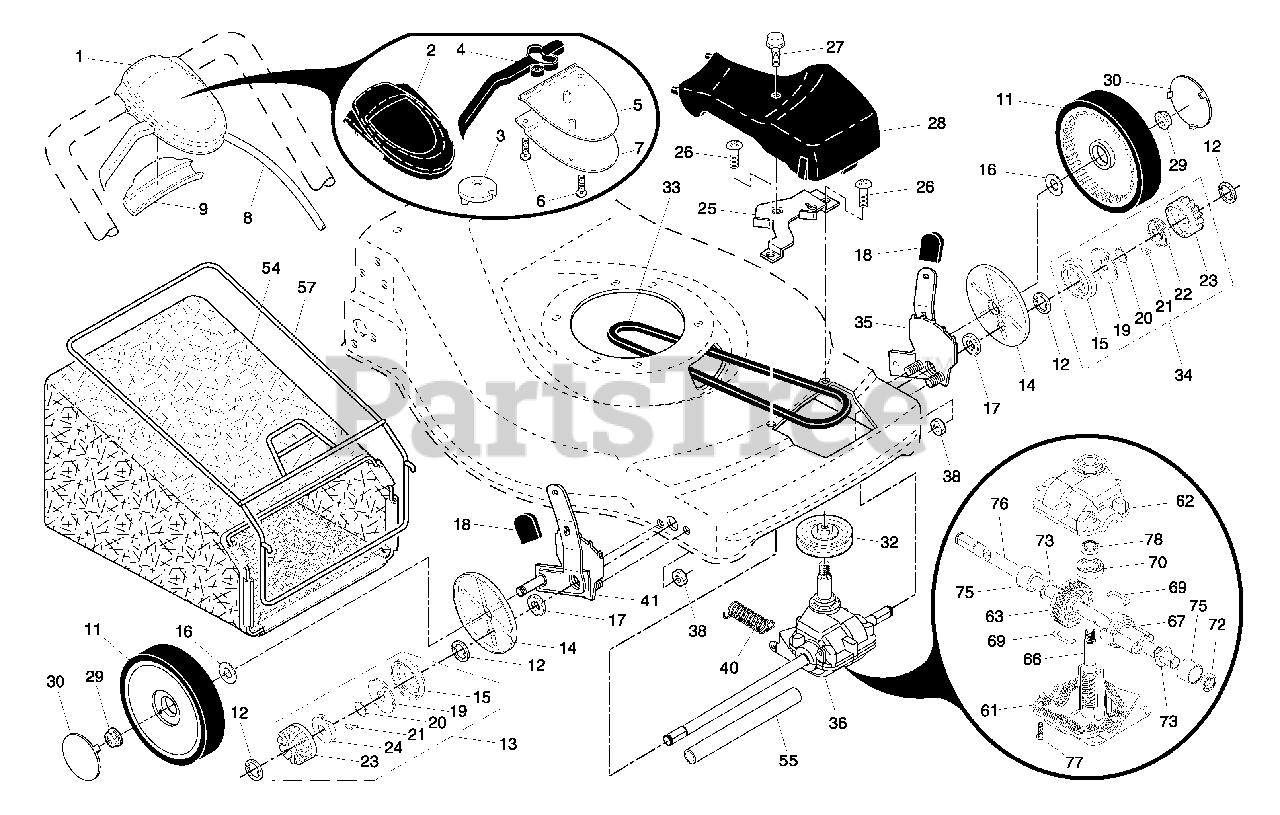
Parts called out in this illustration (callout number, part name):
1	Drive Control Assembly
2	Cover, Drive Control, Top
4	Lever, Drive Control
5	Cover, Drive Control, Bottom
6	Screw, Torx Head #8 x 5/8
7	Mounting Bracket, Drive Control
8	Cable, Drive Control
9	Cap, Drive Control, Bottom
11	Wheel & Tire Assembly
13	Pinion Assembly, RH
14	Dust Cover
15	Seal, Friction
16	Washer, Flat 3/8
17	Bearing, Wheel Adjuster
18	Selector Knob
19	Disc, Drive
20	Spring, Torsion
22	Retainer, Drive, LH
23	Gear, Pinion
24	Retainer, Drive, RH
25	Belt Guide Bracket
26	Screw
27	Pan Head Tapping Screw #10-24 x 2-3/4
28	Drive Cover
29	Locknut, Hex
30	Hubcap
31	Nut, Hex, Flanged
32	Drive Pulley
34	Pinion Assembly, LH
35	Kit, Wheel Adjuster, LH
36	Gear Case Assembly, Complete
38	Locknut, Hex 1/4-20
40	Spring
41	Kit, Wheel Adjuster, RH
54	Grassbag Assembly
55	Driveshaft Cover
57	Frame, Grassbag
61	Case, Lower
62	Case, Upper
63	Gear, 27 Teeth
66	Shaft, Input
69	Wire, Formed
70	Bearing, Ball
72	Seal, Output Shaft
76	Shaft, Output
78	Seal, Input Shaft
